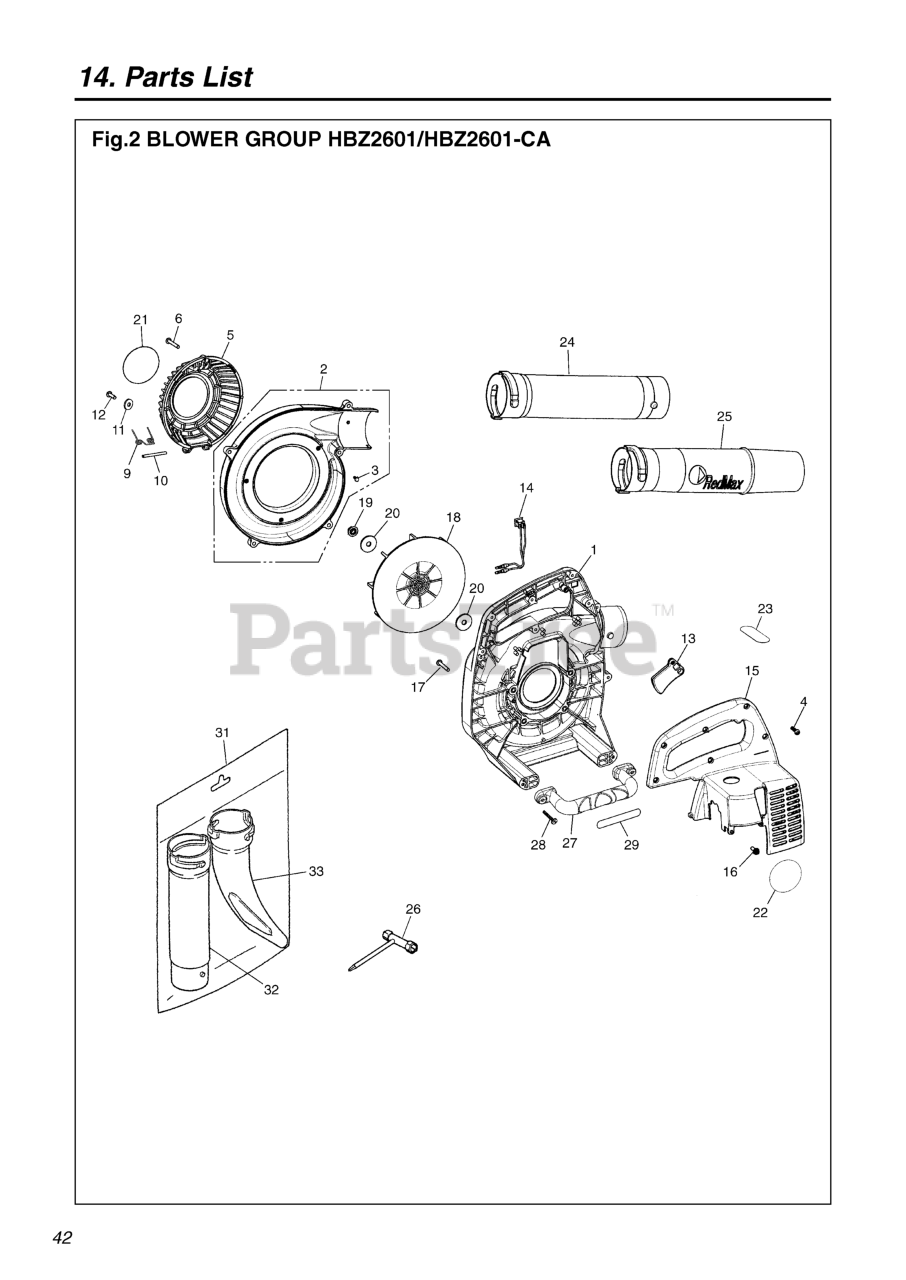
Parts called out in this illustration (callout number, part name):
1	VOLUTE CASE
2	VOLUTE COVER (HBZ2600)
3	SCREW
4	SCREW, TORX (RPLS T4970-52001)
5	GUARD NET
6	SCREW, M4x25 (RPLS.0260-30425)
9	SPRING
10	SHAFT
13	LEVER
14	SWITCH
15	ENGINE COVER
16	BOLT
17	SCREW
18	FAN
20	WASHER
21	LABEL,CAUTION HBZ2601
22	LABEL, RECOIL
23	LABEL (CAUTION)
24	PIPE, STRAIGHT
25	PIPE, END
27	HANDLE
28	SCREW
31	FLAT NOZZLE SET
32	PIPE, STRAIGHT
33	NOZZLE, FLAT
